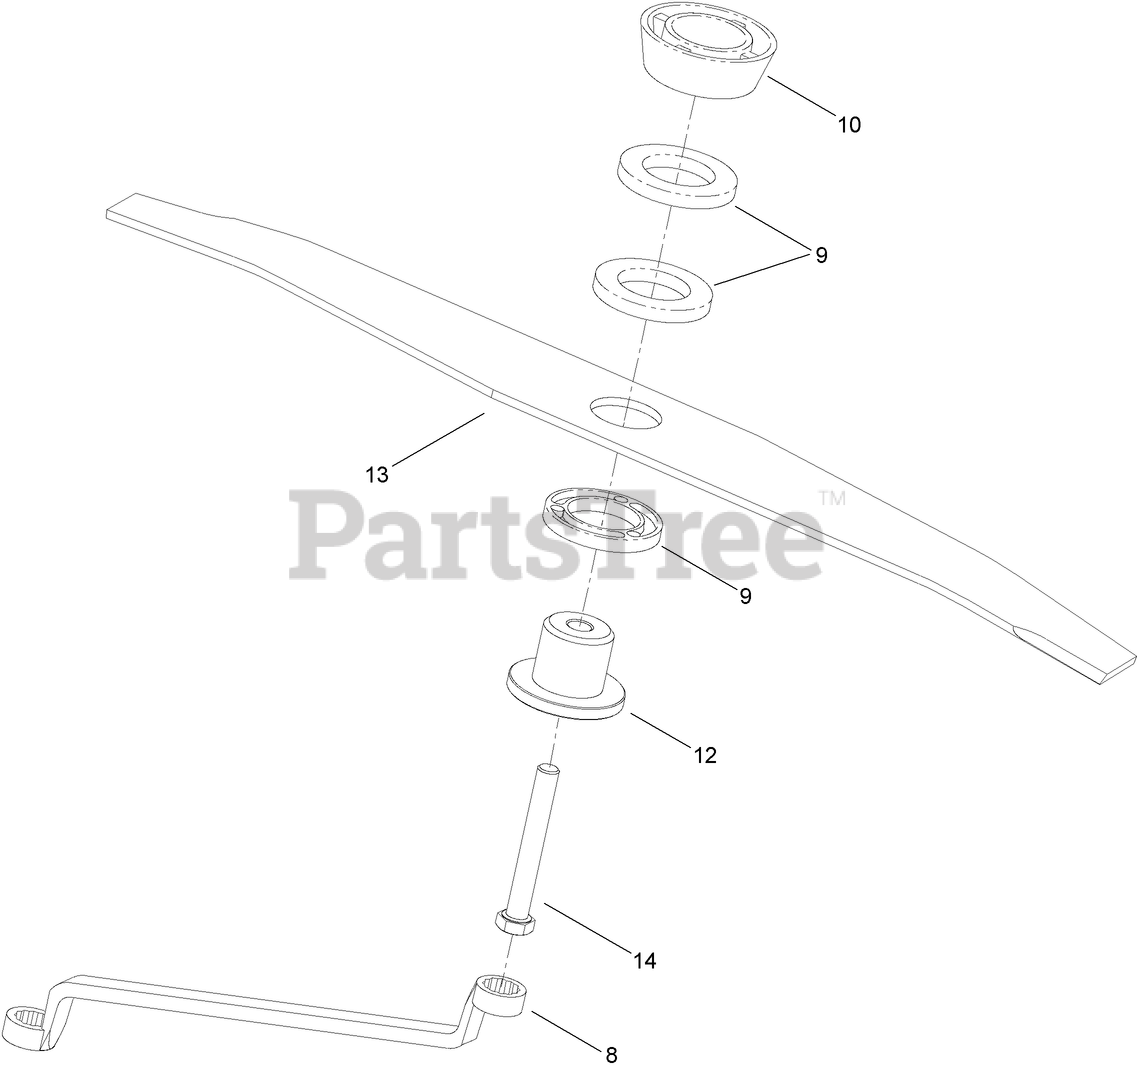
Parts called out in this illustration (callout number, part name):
8	SPANNER
9	SPACER-BLADE, ALUMINIUM
10	SPACER-DISTANCE
12	RETAINER-BLADE
13	BLADE
14	SCREW-SET
